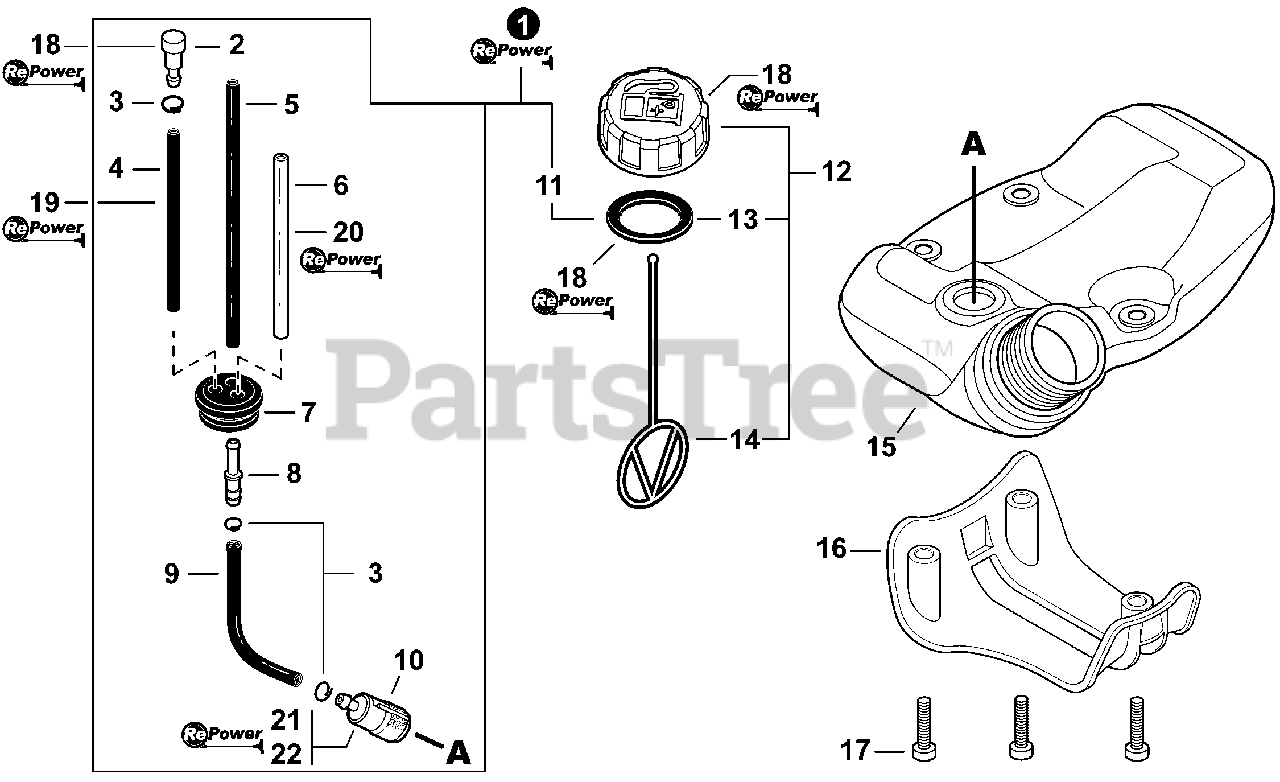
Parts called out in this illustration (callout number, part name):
1	FUEL SYSTEM KIT - REPOWER
2	VENT ASSY
3	CLIP Ø6
4	PIPE, FUEL 3×5×90 BLACK
5	PIPE, FUEL 3×5×74 BLACK
6	PIPE, FUEL 3×6×80 CLEAR
7	GROMMET, FUEL Ø5
8	CONNECTOR, PIPE Ø5ר3.5
9	PIPE, FUEL 3×5×130 BLACK
10	FILTER, FUEL
11	GASKET, FUEL CAP
12	CAP ASSY, FUEL
13	GASKET, FUEL CAP
14	CONNECTOR, CAP L= 123
15	TANK, FUEL
16	GUARD, FUEL TANK
17	BOLT, TORX 5×25
18	CAP/VENT KIT - REPOWER
19	PIPE, BULK - REPOWER 3×5mm BLACK
20	PIPE, BULK - REPOWER 3×6mm CLEAR
21	TUNE-UP KIT - REPOWER
22	FILTER KIT - REPOWER
